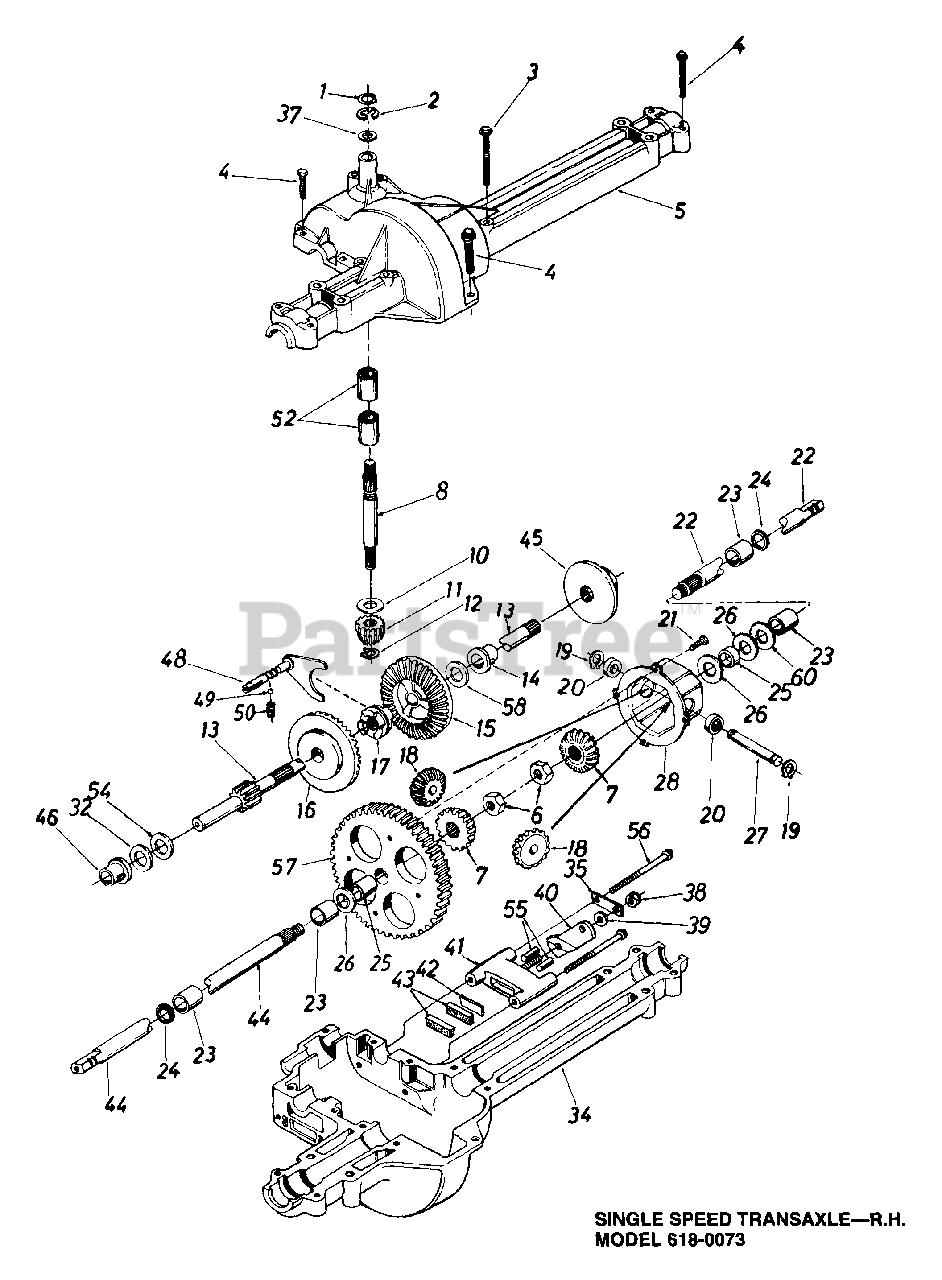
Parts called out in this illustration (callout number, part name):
1	Wire Ring
2	"E"-Ring
3	Hex Wash. TT-Tap Scr. 1/4-20 x 1.75" Lg.
4	Hex Tap Scr. 1/4-20 x 1.25" Lg.
5	Upper Housing
6	Hex Jam Nut 1/2-20 Thd.
7	Miter Gear
8	Input Shaft
10	Thrust Washer 5/8" I.D. x 1.25" O.D.
11	Pinion Input 147
12	Retaining Ring
13	Drive Shaft - R.H. Brake
14	Flange Brg. 5/8" I.D. x 3/4" Lg.
15	Bevel Gear 42T Small I.D.
16	Bevel Gear 42T Large I.D.
17	Clutch Collar
18	Miter Gear 15T (H.D.)
19	Snap Ring
20	Thrust Bearing
21	Pan Head Scr. 1/4-20 x .50" Lg. w/Patch
22	Axle R.H.
23	Sleeve Bearing 3/4" I.D. x 1.0" Lg.
24	Oil Seal 3/4" I.D.
25	Axle Spacer
26	Fl-Wash..760" I.D. x 1.5" O.D.
27	Cross Shaft
28	Differential Can Ass'y.
32	Washer
34	Lower Housing
35	Anti-Rotation Brkt.
37	Washer
38	Hex Nut 5/16-24 Thd.
39	Fl-Wash. .344" I.D. x .875" 0 D.
40	Actuating Arm
41	Brake Yoke
42	Puck Plate
43	Brake Puck
44	Axle L.H.
45	Brake Disc
46	Flange Bearing 5/8" I.D. x 15/16" Lg.
48	Shift Fork Ass'y.
49	Ball Detent .250" Dia.
50	Spring Detent
52	Needle Brg. 5/8" I.D. x 1/2" Lg.
54	Fl-Wash. 5/8" I.D. x 1" O.D. x .020 Thk.
55	Actuating Pin 5/16" Dia.
56	Hex Wash Hd. Self-Tap Scr. 1/4-20 Thd.
57	Differential Gear 58T
58	Fl-Wash. 5/8" I.D. x 1" O.D. x .020 Thk.
60	Washer
